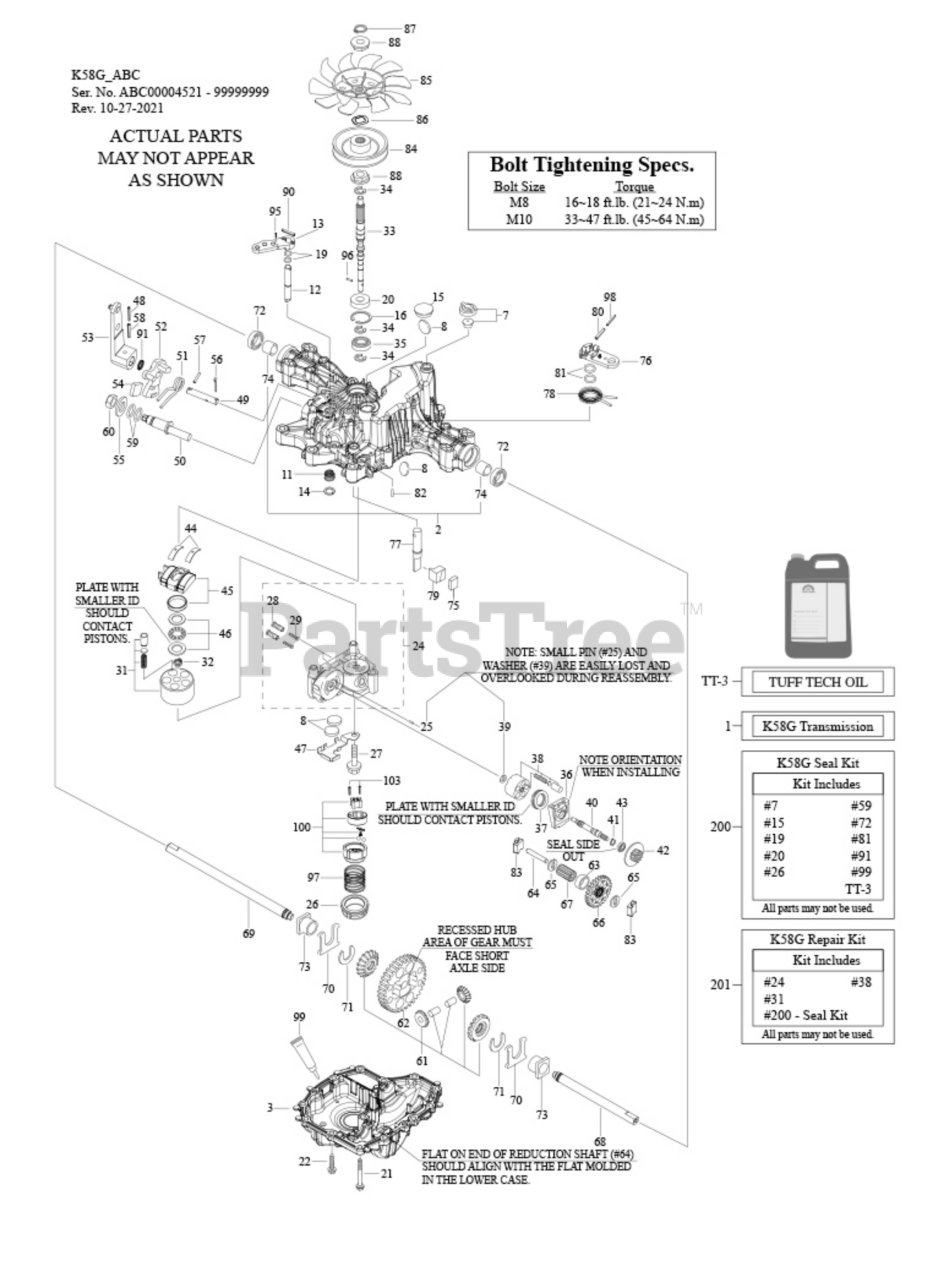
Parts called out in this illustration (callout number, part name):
1	TRANSMISSION ASSEMBLY
2	UPPER HOUSING KIT
7	VALVE ASSEMBLY-VENT
21	TAP SCREWPING 8X
22	TAP SCREWPING 8X
24	SECTION ASSEMBLY-CENTER
28	VALVE-IDS 1.2
31	BLOCK KIT-PISTON &
32	SPRING-CYL BLOCK
33	SHAFT-PUMP INPUT
35	BALL BEARING
36	HOUSING-MOTOR
38	BLOCK KIT-PISTON &
44	BEARING-CRADLE THRUST
45	SWASHPLATE ASSEMBLY
46	BEARING ASSEMBLY-THRUST PM
47	HOLDER-MAGNET
48	ROLL PIN 3.5 x 4
49	SHAFT-CONTROL
51	TORSION SPRING
52	ARM-CONTROL A
53	LEVER-CONTROL F
55	FLAT WASHER 12
56	COTTER PIN 1/8 x .75
57	SPRING PIN 6 x 3
58	ROLL PIN 6 x 4
61	DIFFERENTIAL GEAR ASSEMBLY
63	COLLAR-FINAL PINION
64	SHAFT-REDUCTION
65	THRUST WASHER
66	GEAR-REDUCTION
67	GEAR-FINAL PINION
68	AXLE SHAFT (LH)
69	AXLE SHAFT (RH)
70	THRUST WASHER
71	RING-"C" AXLE
72	AXLE OIL SEAL
73	BUSHING-FLG AXLE
78	SPRING-BRAKE RETUR
79	ACTUATOR-BRAKE
80	SPRING PIN 5 x 3
82	SPRING PIN 4 x 1
83	BUSHING-SUPPORT
88	COLLAR-SPLINE
90	SPRING PIN 3 x 2
95	SPRING PIN 3 x 1
96	PIN 2.5 x 9.8
97	SPRING-CHARGE PUMP
98	SPRING PIN 3 x 32
100	PUMP KIT-CHARGE
200	KIT-SEAL K58G NX-15
201	REPAIR KIT K58G NX-15
